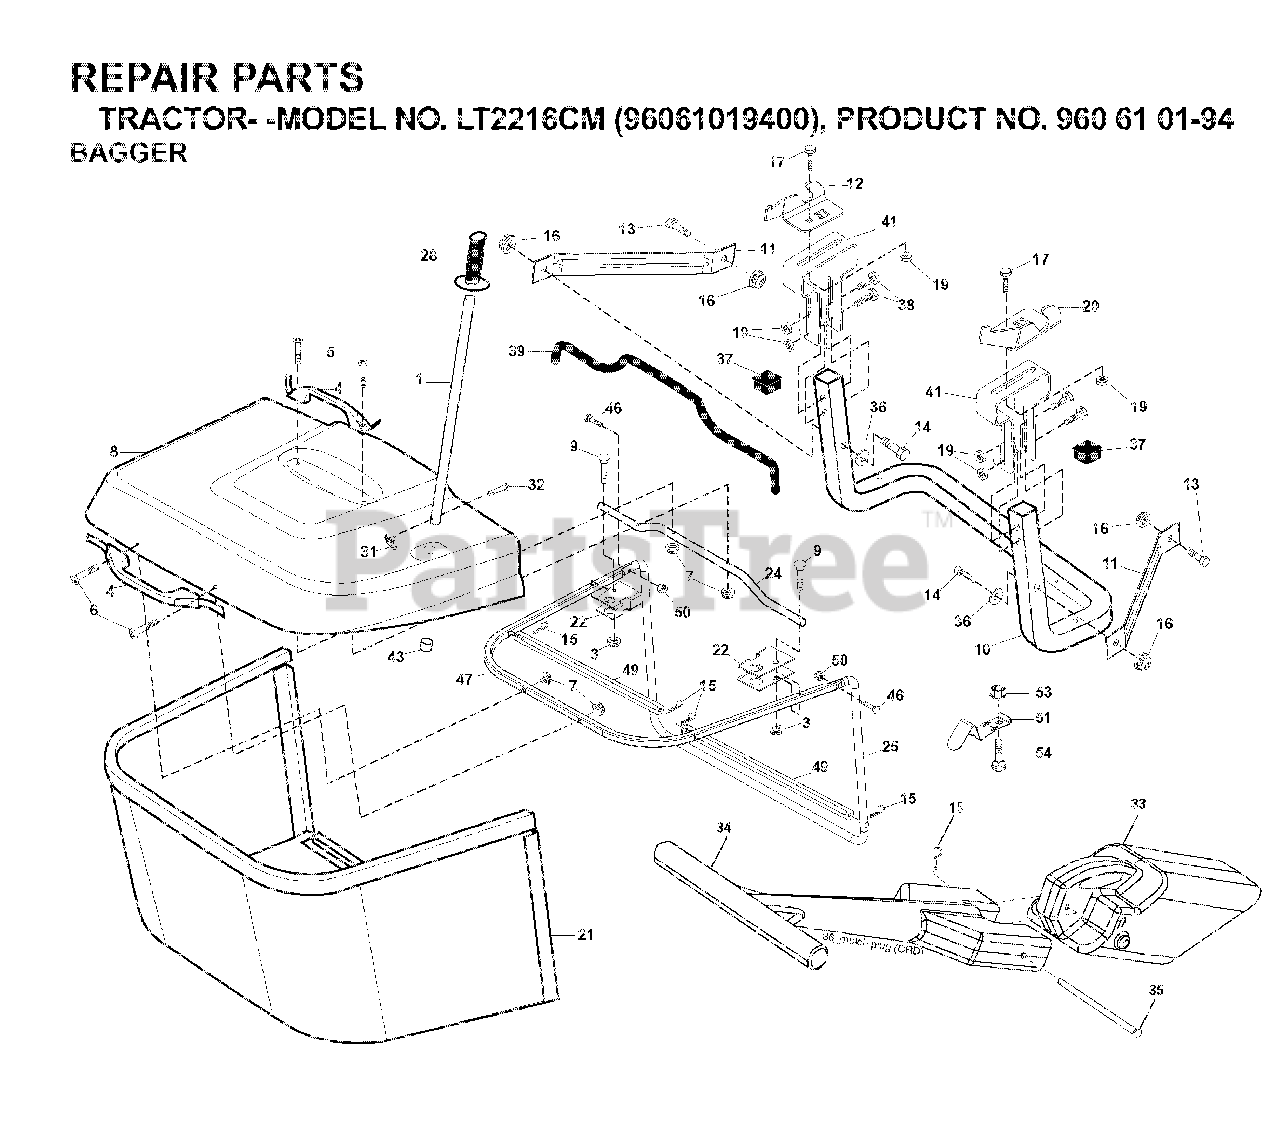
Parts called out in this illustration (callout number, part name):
1	TUBE HANDLE
3	NUT T
5	SCREW.PAN.HEAD
11	BRACKET
14	BOLT-HEX EAK
15	RETAINER-SPRNG RB
16	NUT LOCK FLG 3/8-16 UNC
17	BOLT
19	NUT LOCK HEX FLANGE 5/16-18
20	BRKT.PIVOT.RH.CRD
21	BAGGER.ASM.CRD.2007
22	BRACKET
24	TUBE
28	GRIP.HANDLE.BLACK
31	RETAINER CLIP
32	RIVET,DRILLED
33	PLUG
35	PIN
38	BOLT.5/16-18X2.5
41	BRKT, BAGGER
43	PLUG, TUBING END
46	BOLT.CARRIAGE.5/16-18
50	NUT.71038.31-18.HEX.NYLOCK
53	NUT
54	BOLT
